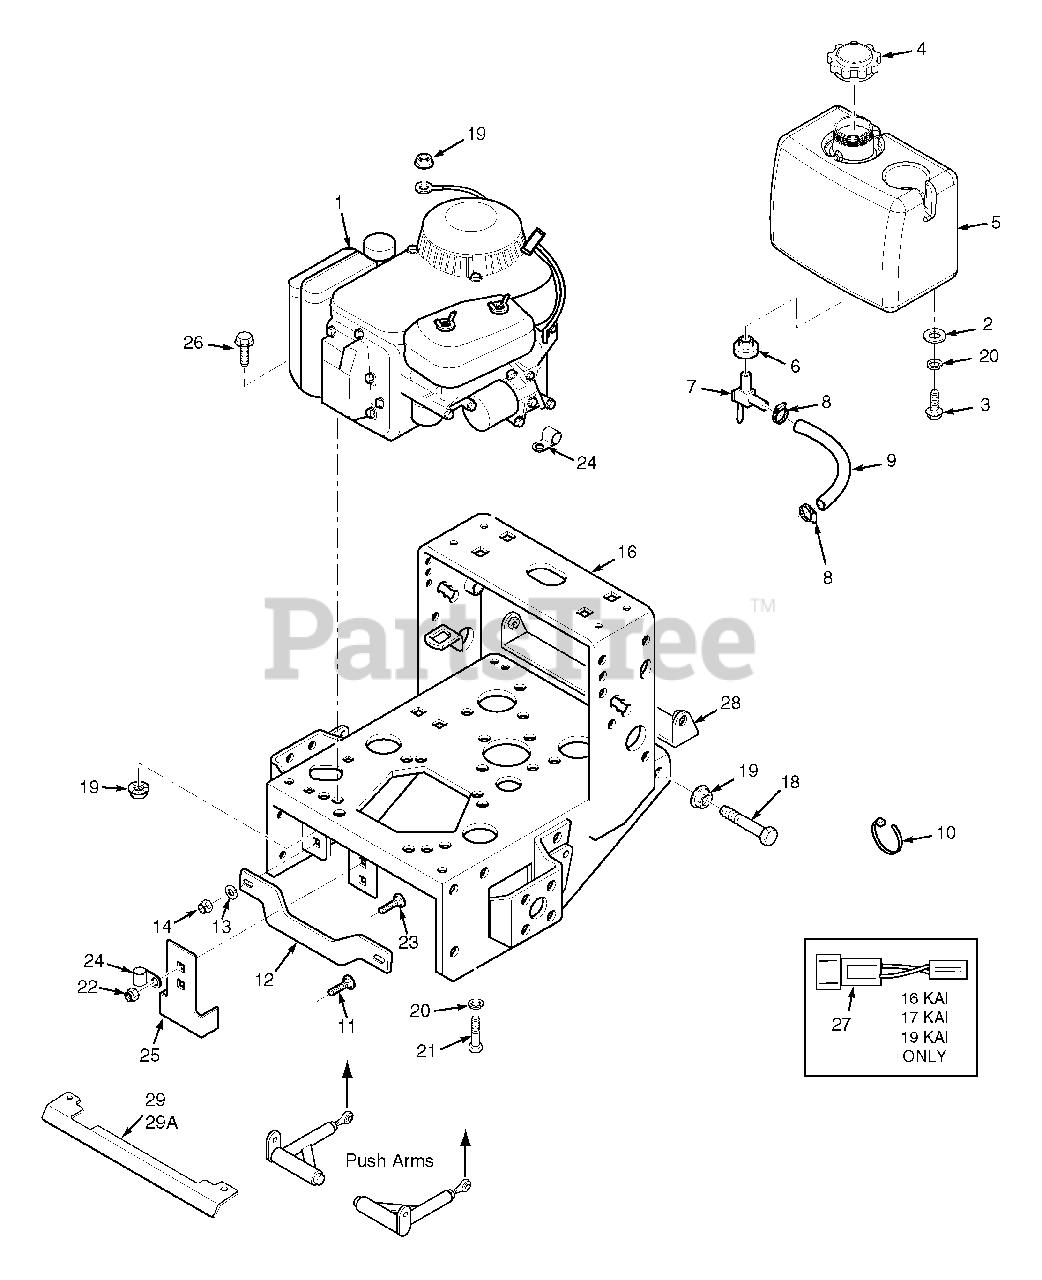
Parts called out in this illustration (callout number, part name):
1	Engine, 16KAI Kawasaki
2	Flatwasher, 5/16 (.375 x .875 x .083)
3	Capscrew, 5/16-18 x 1" Hex Head
4	Cap, Fuel Tank
5	Fuel Tank Assy.
6	Bushing
7	Valve, Fuel Shut-off
8	Clamp, Fuel Hose
9	Fuel Hose, 1/4 ID x 18"
10	Cable Tie
11	Carriage Bolt, 3/8-16 X 1-1/4"
12	Brace
13	Flat Washer .391 x .938 x .105
14	Nut, 3/8-16 Elastic Stop
15	Nut, 1/4-20 Elastic Stop
16	Engine Deck, 16" Wide, w/decals
17	Bolt, 1/4-20 x 1-1/4" Carriage
18	Bolt, 5/16-18 x 2" Hex Head
19	Nut, 5/16-18 Serr. Flange
20	Lock Washer 5/16"
21	Bolt, 5/16-18 x 1" Serrated Flange Hex Head
22	Nut, 5/16-18 Elastic Stop
23	Carriage Bolt, 5/16-18 x 1"
25	Clutch Bracket
26	Cap Scrw, 5/16-18 x 1.50" Sr. Flg
27	Wire Harness Adapter
28	Pulley Guard, 16" Frame
29	Heatshield
29A	Heatshield
